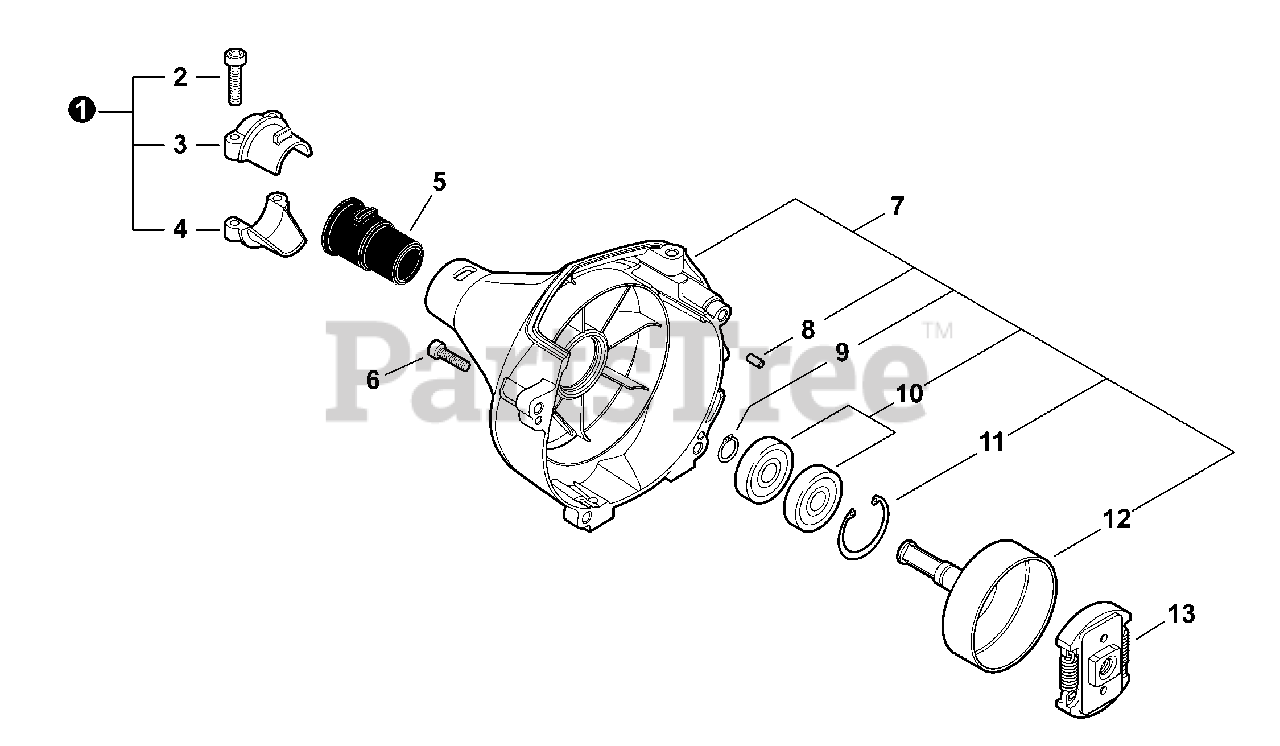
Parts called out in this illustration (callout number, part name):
1	HOLDER KIT
2	SCREW - 5×20
3	HOLDER, MAIN PIPE - UPPER
4	HOLDER, MAIN PIPE - LOWER
6	SCREW - 4×16 -- TORX
7	FAN CASE ASY
8	PIN, LOCATING
9	RING, RETAINING - 12
10	BEARING, BALL - 6001
11	RING, RETAINING - 28
12	DRUM, CLUTCH
13	CLUTCH ASY
